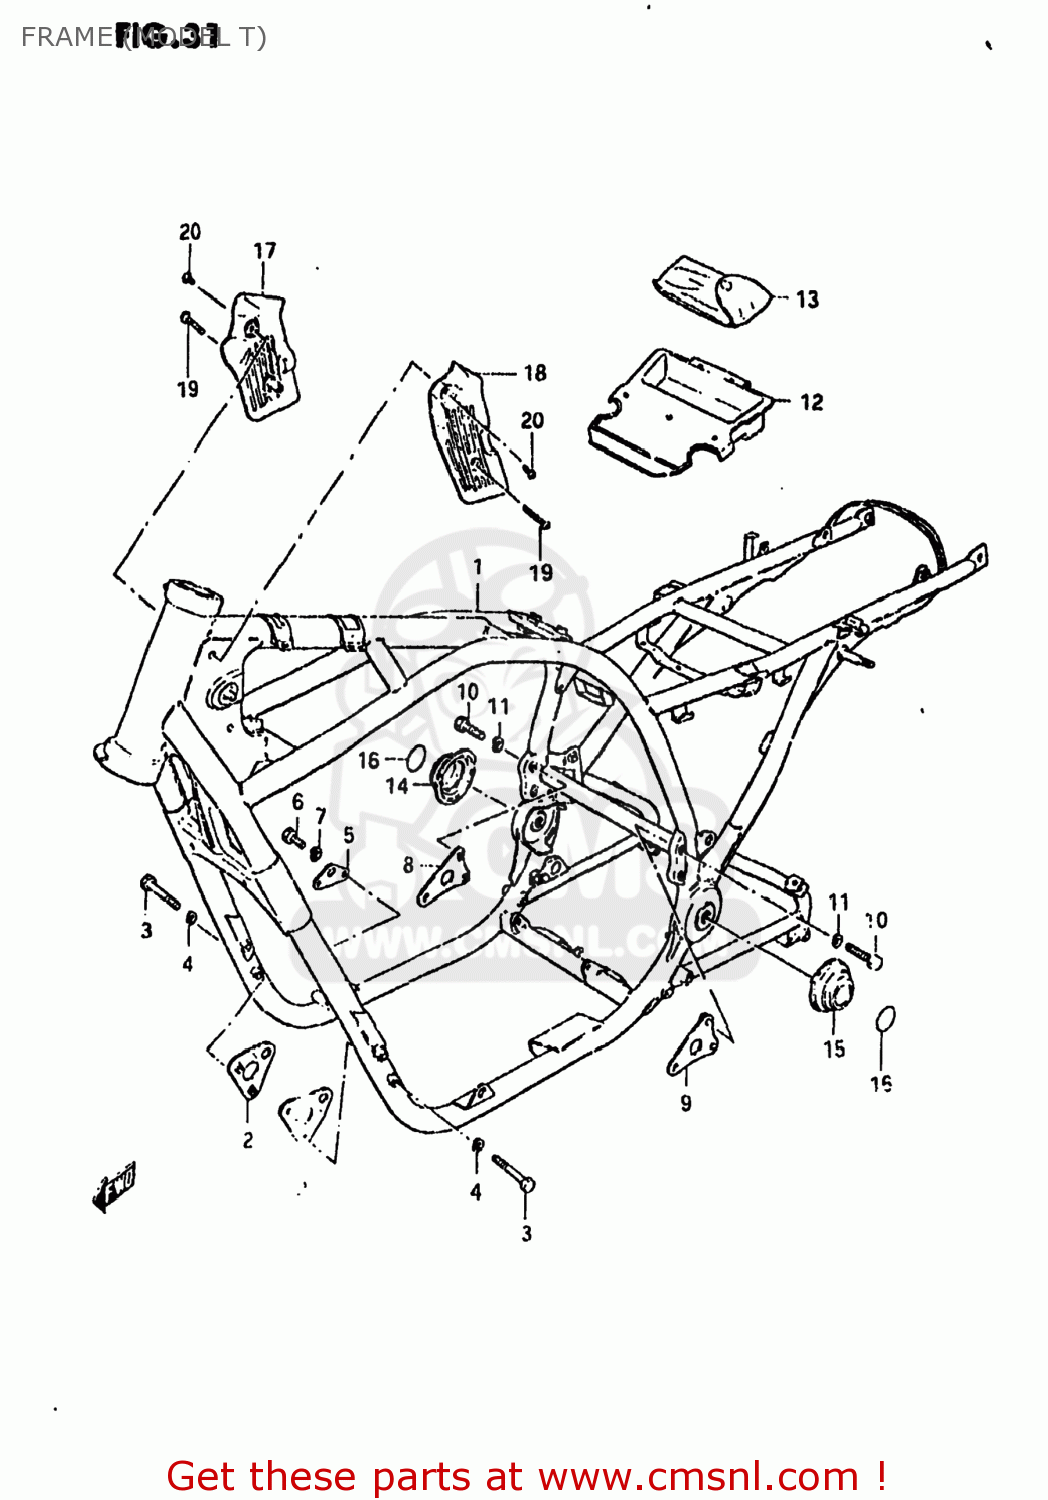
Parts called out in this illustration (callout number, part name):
1	FRAME
2	PLATE,ENGINE MOUNTING
3	BOLT
4	LOCK WASHER
5	PLATE,ENGINE MOUNTING
6	BOLT
7	LOCK WASHER
8	PLATE,ENGINE MOUNTING
9	PLATE,ENGINE MOUNTING
10	BOLT 8X40
11	LOCK WASHER
12	HOLDER,TOOL
13	TOOL SET
14	COVER,REAR SWING ARM PIVOT
15	COVER,REAR SWING ARM PIVOT
16	TAPE,REAR SWING ARM PIVOT
17	COVER,FRAME HEAD,RIGHT
18	COVER,FRAME HEAD,LEFT
19	SCREW, LOWER
20	SCREW
